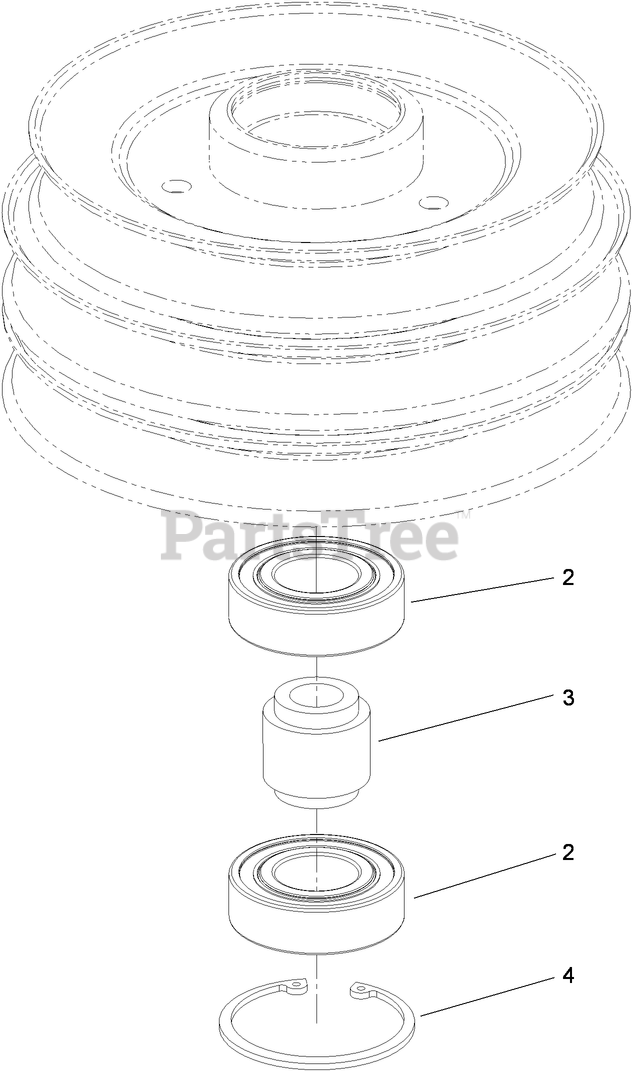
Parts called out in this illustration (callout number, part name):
2	BEARING-BALL
3	SPACER-BEARING
4	RING-SNAP
